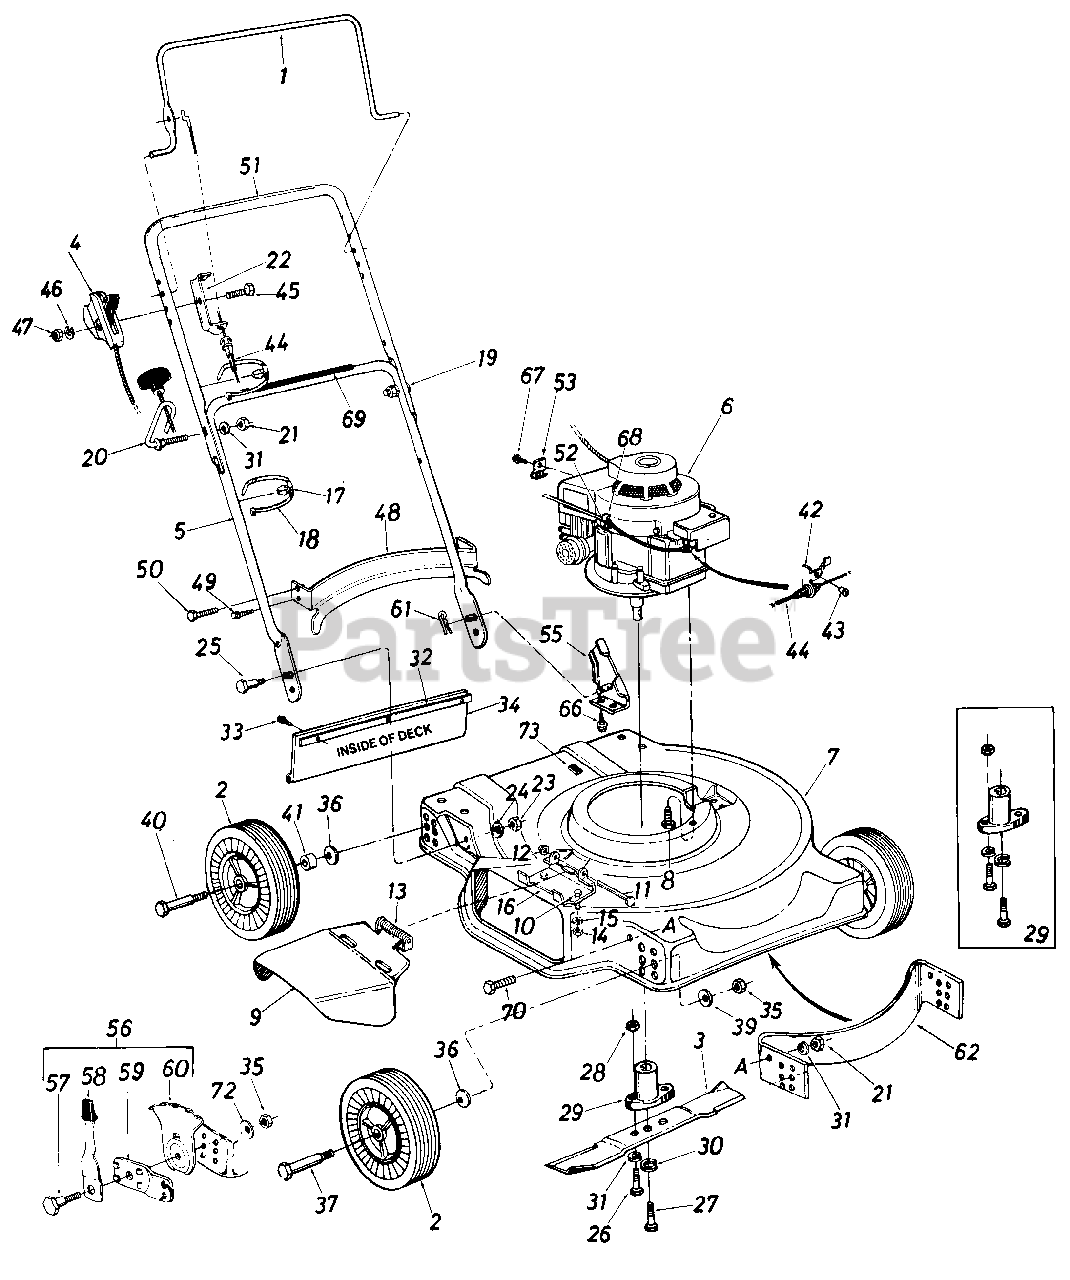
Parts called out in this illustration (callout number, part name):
1	Control Handle-R.H.
2	Wheel-Plastic Rim (7 x 1.5)
3	22" Blade
4	Throttle Control Ass'y.-41"
5	Lower Handle (Chrome)
6	Engine
7	22" Deck Assy.
8	Hex Wash. Hd. TT-Tap Scr. 3/8-16 x 1.00" Lg.
9	Chute Deflector Ass'y.
10	Hex Bolt 1/4-20 x .50" Lg.*
11	Hinge Pin 1/4" Dia. x 3.88 Lg.
12	Push Cap .25" Rod
13	Torsion Spring
14	Hex Nut 1/4-20 Thd.*
15	L-Wash. 1/4" I.D.*
16	Deflector Hinge Plate
17	Plastic Cable Anchor
18	Cable Tie
19	Curved Carriage Bolt 5/16-18 x 1.38" Lg.
20	Rope Guide Bolt
21	Hex Nut 5/16-18 Thd.*
22	Cable Mtg. Brkt.
23	Hex Ins. L-Nut 5/16-18 Thd.
24	Bell-Wash. .345" I.D. x .88" O.D.
25	Shld. Bolt .437" Dia. x .268
26	Hex Bolt 5/16-24 x 1.00" Lg. (Grade 5)
27	Hex Bolt 3/8-24 x 2.25" Lg. (Grade 5)
28	Hex Nut 5/16-24 Thd.*
29	Blade Adapter Kit
30	L-Wash. 3/8" I.D.-H.D.
31	L-Wash. 5/16" I.D.*
32	Retainer Strip
33	Hex Wash. Hd. AB-Tap Scr. 1/4" x .62" Lg.
34	Rear Flap Ass'y.
35	Hex Nut 3/8-16 Thd.*
36	Bell-Wash. .400" I.D. x .88"
37	Front Axle Bolt
39	Bell-Wash. .39" I.D. x 1.13" O.D.
40	Rear Axle Bolt
41	Spacer .511 I.D. x .70" O.D.
42	Cable Bracket
43	Pop Rivet .156" Dia. x .379
44	49" Control Cable-Blue
45	Hex Bolt 1/4-28 x 1.75" Lg.
46	Spring Wash. .270" I.D. x .57" O.D.
47	Hex Nut 1/4-28 Thd.
48	Rear Baffle**
49	Truss Mach. B-Tap Scr. #10 x .50" Lg.
50	Hex Bolt 5/16-18 x .75" Lg.*
51	Upper Handle (Chrome)
52	Hex B" Tap Scr. #10 x .38"
53	Casing Clamp
55	Handle Mount Brkt. Ass'y.-L.H.
56	Height Adjuster Ass'y. Comp.-R.H .
57	Shoulder Bolt .500" Dia. x .357
58	Spring Lever Ass'y. w/Knob
59	Pivot Bar
60	Index Plate
61	Hairpin Cotter
62	Front Baffle
66	Hex Wash. Hd. Self-Tap Scr. 5/16-18 x .50" Lg.
67	Hex Wash. Hd. AB-Tap Scr. #8 x .38" Lg.
68	Cable Clip
69	Instruction Label-Handle
70	Hex Bolt 3/8-16 x .75" Lg.
72	Belleville Wash. .39 I.D. x 1.4 O.D.
73	Plastic Plug
